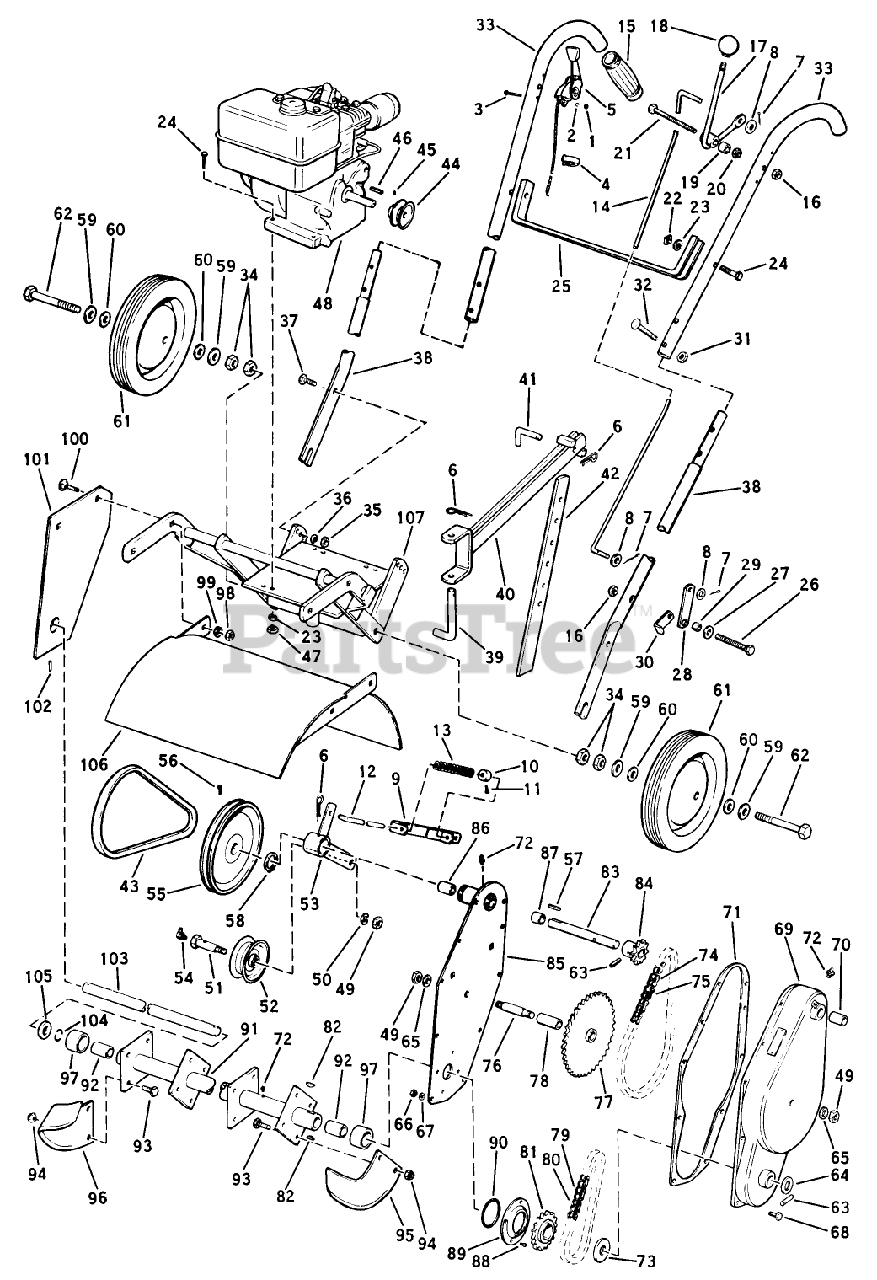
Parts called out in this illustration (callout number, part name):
2	Lockwasher
3	Machine Screw #8-32 x 1-1/2 Lg.
4	Cable Clip
5	Throttle Control Assembly
7	BUMPER-RUBBER
9	Spring Bracket Assembly
11	Set Screw
12	Engine 8 H.P.
13	SRV BULLT 437B
17	Control Lever Assembly
22	Square Nut 5/16-18
24	Capscrew 5/16-18 NC x 1-1/2 Lg.
26	Capscrew 3/8-24 x 1-3/4 Lg.
28	Shifting Lever
32	Square Nut 5/16-18
34	Hex Jam Nut 1/2-13
35	Hex Nut 3/8-16
36	Lockwasher
37	Capscrew 3/8-16 x 1-1/4 Lg.
38	Handle Bar Tube Assembly
40	Beam Assembly
41	Selector Pin
42	Depth Bar
47	Hex Nut 5/16-18
49	Hex Jam Nut
52	Idler Pulley
53	Idler Arm Assembly
56	Set Screw
59	Washer 1/2 SAE
60	Rubber Washer
61	Wheel Assembly 10 x 1.75
62	Hex Head Axle Bolt 1/2-13 x 4 Lg.
63	Roll Pin
65	Lockwasher, Shakeproof
66	Hex Nut
68	Capscrew
69	Cover Assembly
72	Grease Fitting
73	Thrust Washer
74	Chain #41-1/2 Pitch, 55 Links
76	Intermediate Shaft
77	Sprocket Cluster Assy
78	Bushing
79	Extension-Chute
82	Woodruff Key
84	Input Sprocket and Hub Assv.
85	Back Plate Assembly
88	Self Tapping Screw #8-32 x 1/4 Lg.
89	Oil Seal Retainer
91	Rotor Tube Assembly
96	Tine LH
100	PEDAL-BRAKE *R
101	Side Plate Assembly
102	Roll Pin
103	Rotor Shaft
106	Hood Assembly
